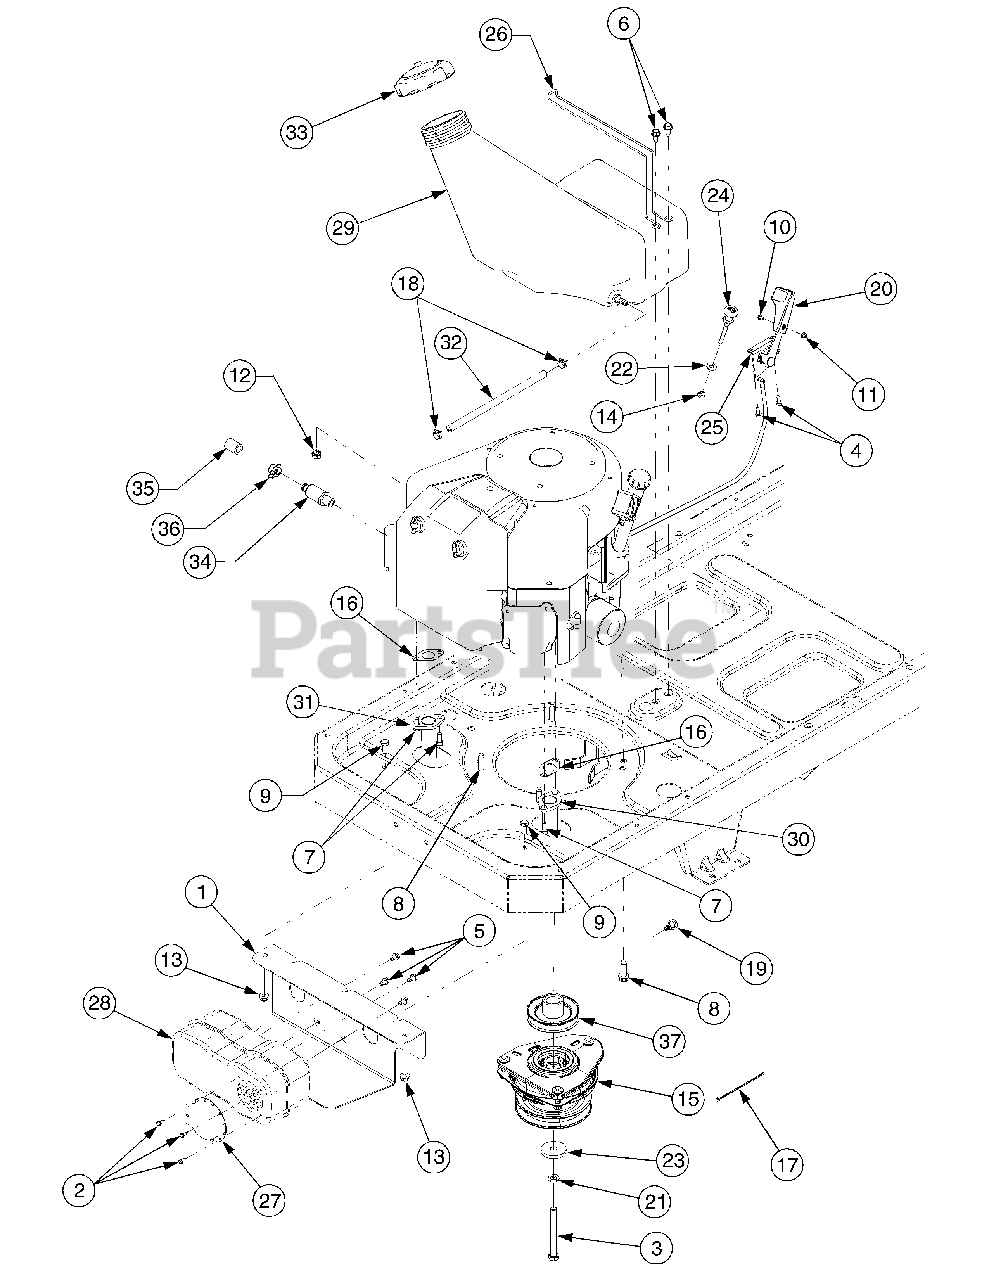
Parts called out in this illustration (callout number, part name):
1	Bracket, Muffler Mounting
2	Screw, Hex Wash. Hd. Tapp #8-18 x .5
3	Screw, Hex Cap, 7/16-20 x 4.0 GR5
4	Screw, Hex Wash. Hd. Tapp #12-16 x .5
5	Screw, Hex Wash. Hd. Tapp 1/4-20 x .5
6	Screw, Hex Wash. Hd. Tapp 5/16-12 x .75
7	Screw, Socket Hd. 5/16-18 x .75
8	Screw, Hex Wash. Hd. Tapp 3/8-16 x 1.25
9	Screw, Hex Cap, 5/16-18 x .75 GR5
10	Screw, Truss Hd. Mach. #8-32 x .375
11	Nut, Hex, #8-32
12	Nut, Hex Sems, 1/4-20
13	Nut, Hex Insert Lock, 5/16-18 GR5
14	Nut, Hex Flange Lock, 3/8-16 GR5
15	Clutch Assembly, Electric PTO
16	Gasket, Exhaust
19	Clip, Cable Retainer
20	Knob, Throttle Control
21	Washer, Lock, 7/16
22	Washer, Flat, .406 x .875 x .059
23	Washer, Flat, .438 x 1.75 x .25
24	Cable, Choke, 47 Lg
25	Cable, Throttle, 39.0 Lg
26	Wire, Tank Mounting
27	Deflector, Muffler
28	Muffler
29	Tank, Fuel, 3.0 Gal.
30	Pipe, Exhaust RH
31	Pipe, Exhaust LH
32	Hose, Fuel Line 14in
33	Cap, Fuel
34	Valve, Oil Drain
35	Hose, Oil Drain Extension
36	Cap, Oil Drain Valve
37	Pulley, Drive
